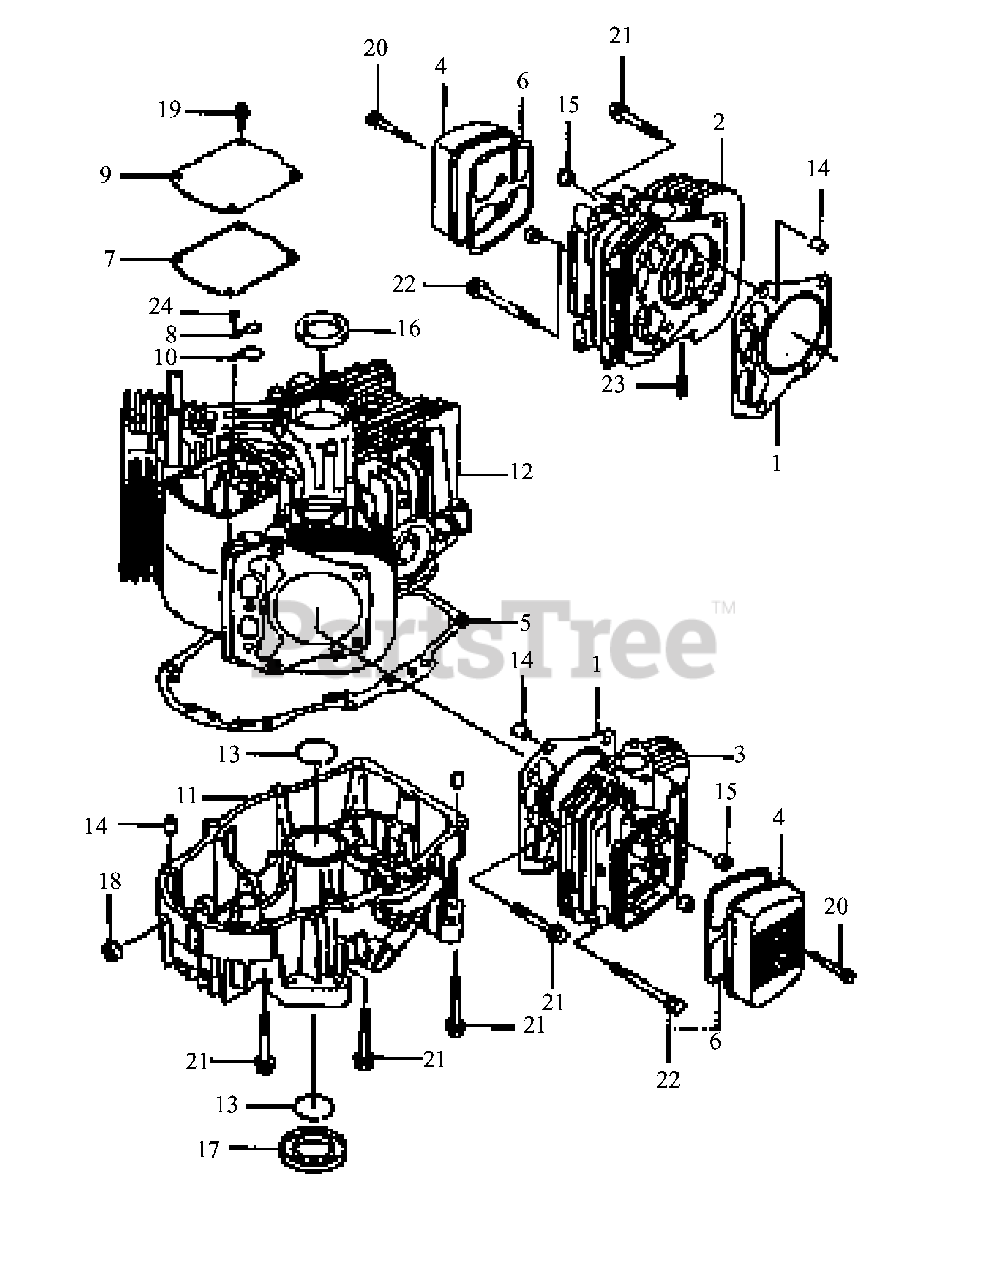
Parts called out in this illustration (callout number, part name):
2	Head-Cylinder # 1
3	Head-Cylinder # 2
4	Case-Rocker
5	Gasket, Crankcase
6	Gasket-Rocker Cover
7	Gasket-Breather
11	Cover-Crankcase
12	Crankcase
